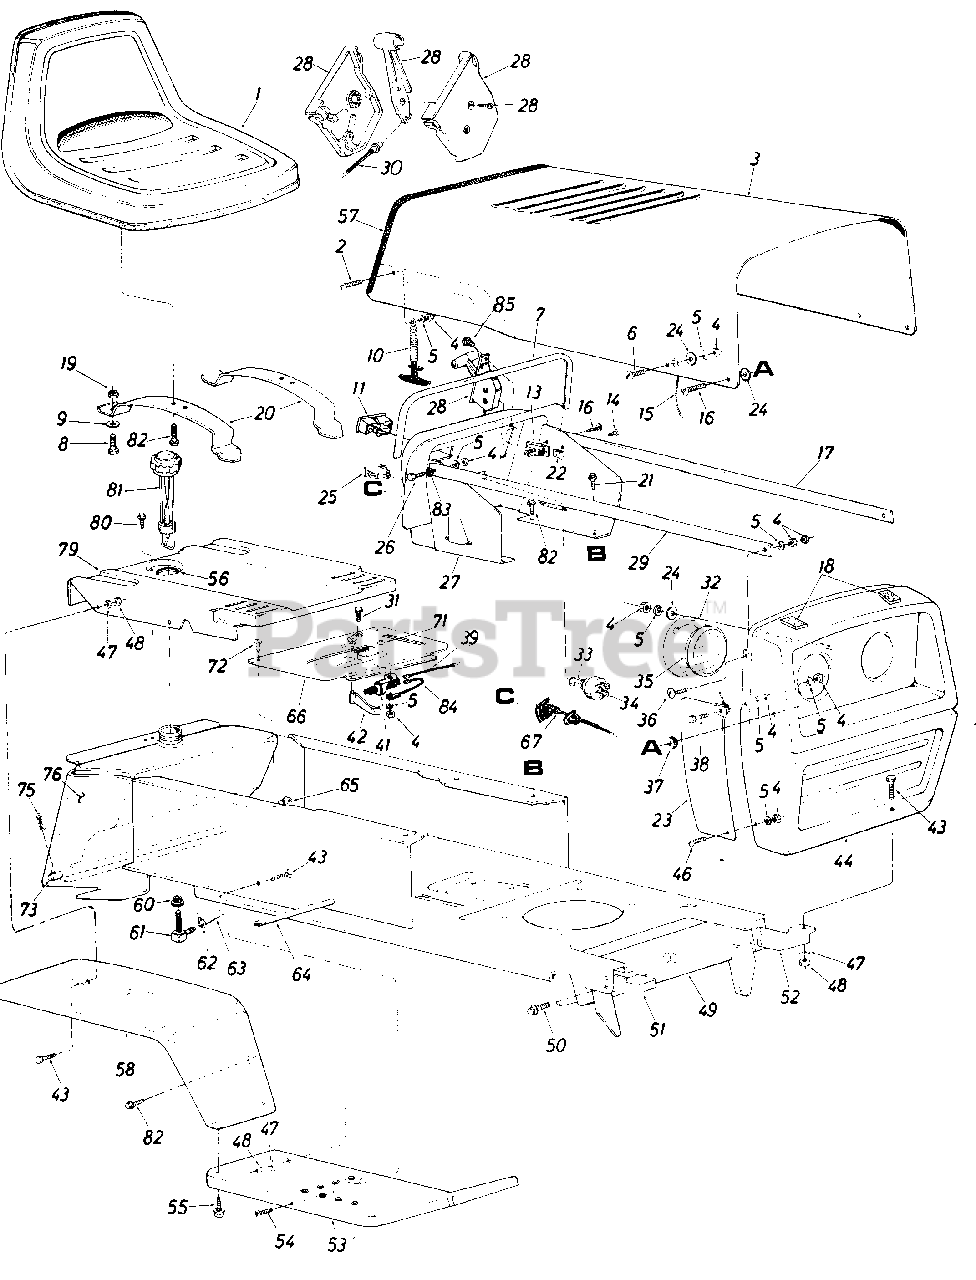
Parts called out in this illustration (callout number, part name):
1	Seat Assembly
2	Truss Mach. Scr. 1/4-20 x .50" Lg.*
5	L-Wash. 1/4" Scr.*
6	Truss Mach. Scr. 1/4-20 x .50" Lg.*
7	Vinyl Molding Strip-29"
8	Hex Nylon Scr. 1/2-13 x .75" Lg.
9	Fl-Wash. .50" I.D. x 1.00" O.D. x .090
10	Hood Latch Ass'y.
11	Ammeter
13	Circuit Breaker 8 Amp.
14	Hex Tap Scr. #10 x .50" Lg.*
15	Hood Stop
16	Truss Mach. Scr. 1/4-20 x .75" Lg.*
17	Grille Positioning Rod
18	PVC Foam Strip 1/2 x 1.00" x 2.00" Lg.
19	Hex Nut 1/2-13 Thd.
22	Speed Nut #10Z
23	Grille Side Panel-R.H.
24	Fl-Wash. 1/4" I.D.
25	Light Switch
26	Truss Hd. Scr. 1/4-20 x 1.00" Lg.*
27	Dash Panel Ass'y.
28	Throttle Control Box Comp.
29	Grille Positioning Rod
30	Throttle Control Cable
31	Hex Bolt 1/4-20 x .50" Lg.
32	Head Lamp Retainer
33	Ignition Key
34	Ignition Switch
35	Head Lamp
36	Truss Machine Scr. 1/4-20 x .75" Lg.*
37	Rubber Wash. .50" I.D. x 1.00 O.D. x .25 Thk.
38	Truss Mach. Scr. 1/4-20 x .50" Lg.*
39	Reverse Lockout Wire
41	Safety Switch
42	Switch Actuator Spring Lever
43	Hex Scr. 5/16-18 x .75" Lg.*
44	Grille Ass'y. (Painted)
46	Truss Mach. Scr. 1/4-20 x .50" Lg.*
47	L-Wash. 5/16" Scr.*
48	Hex Nut 5/16-18 Thd.*
49	Lower Frame Ass'y.
50	Hex Thd. Rolling Scr. 5/16" x.75" Lg.
51	Grille Mount Brkt.-R.H.
52	Grille Mount Brkt.-L.H.
53	Running Board-R.H.
54	Truss Mach. Scr. 5/16-18 x .75" Lg.*
55	Hex Thd. Rolling Scr. 5/16-24 x .75" Lg.
56	Grommet
57	Vinyl Moulding Strip-30"
58	Fender Ass'y.-R.H.
60	Bushing
61	9Oø Nipple
62	Hose Clamp 3/8"
63	Gas Line 46" Lg.
64	Running Board Rod
65	Speed Nut #10-24
66	Transmission Cover Ass'y.
67	Choke Control Comp.
71	Snap Bushing
72	Truss Hd. Scr. #10 x .50" Lg.
73	Hitch Rod
75	Internal Cotter Pin
76	Gas Tank
79	Seat Plate
80	Hex Thd. Rolling Scr. 5/16-24 x .75" Lg.
81	Gas Gauge
82	Hex Thd. Rolling Scr. 5/16-24 x .75" Lg.
83	External Wash. 1/4" I.D.
84	Electric Wire
85	Truss Mach. AB-Tap Scr. #10 x .50" Lg.
